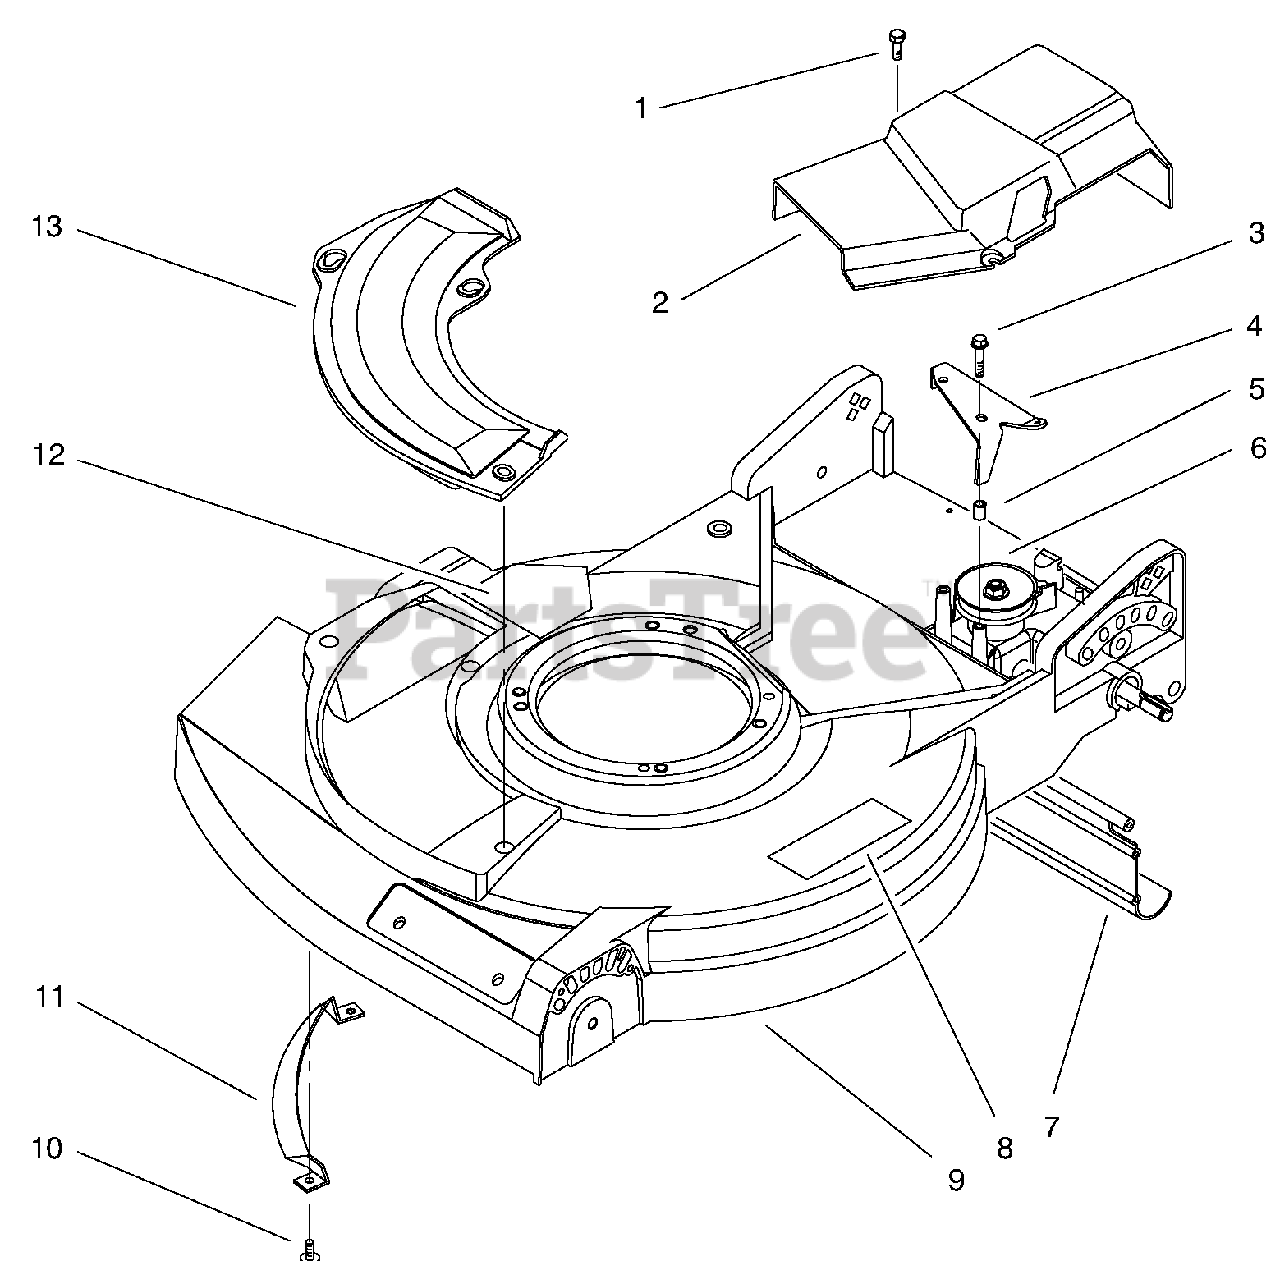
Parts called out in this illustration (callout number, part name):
1	Screw-Hex Washer Hd. Thread Forming
2	Cover-Transmission
3	Screw
4	Bracket-Actuator
5	Bushing-Spacer
6	Gear Case Assembly
7	Shield-Trailing
8	Decal-Warning
9	Housing-21" (Incl. Ref. #8 & 12)
10	Screw-Hex Washer Hd.
11	Bar-Toe
12	Decal-Danger
13	Plate-Cover
